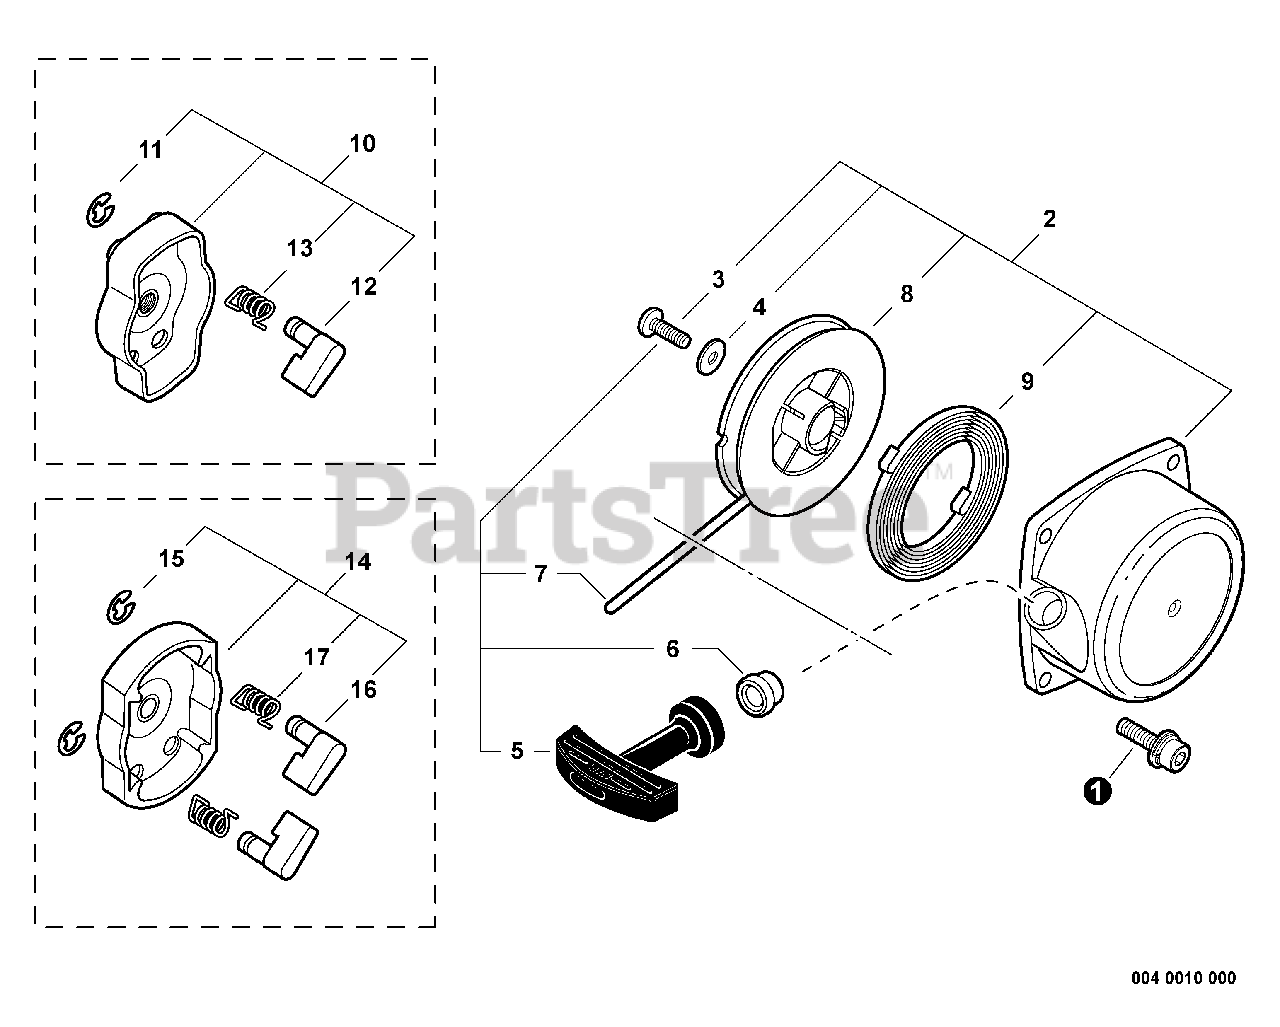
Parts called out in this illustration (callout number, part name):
1	BOLT 4×18
2	STARTER ASSY
4	WASHER
5	GRIP, STARTER
6	GUIDE, ROPE
7	ROPE, STARTER 3.8×1400
8	REEL, ROPE
9	SPRING, RECOIL
10	PAWL ASSY, STARTER
11	E-RING 4
12	PAWL, STARTER
13	SPRING, RETURN
14	PAWL ASSY, STARTER
15	E-RING 4
16	PAWL, STARTER
17	SPRING, RETURN
